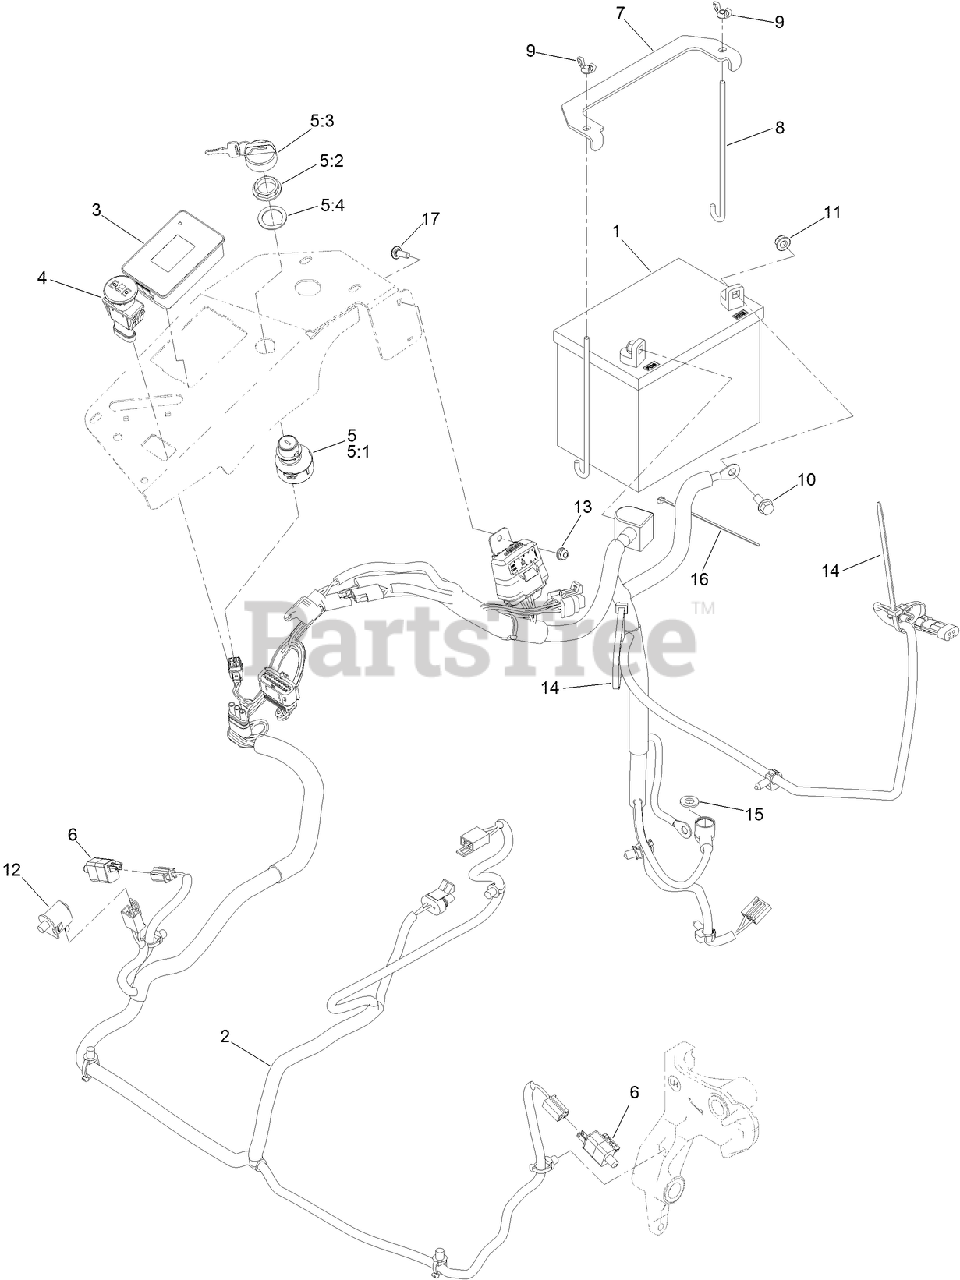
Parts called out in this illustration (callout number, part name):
1	BATTERY-DRY
2	WIRE HARNESS ASM
3	METER-HOUR
4	SWITCH-PTO, SEALED
5	IGNITION SWITCH ASM
5:1	Deck ASM
5:2	NUT-MOUNTING
5:3	IGNITION KEY SET
5:4	WASHER-BACKUP
6	SWITCH
7	STRAP-TIE DOWN, BATTERY
8	BOLT-HOLDDOWN
9	WINGNUT
10	SCREW-HH
11	NUT-HF, NI
12	SWITCH-BAIL
13	NUT-HF
14	TIE-PLASTIC
15	WASHER-FLAT
16	TIE-CABLE
17	BOLT-CARR
